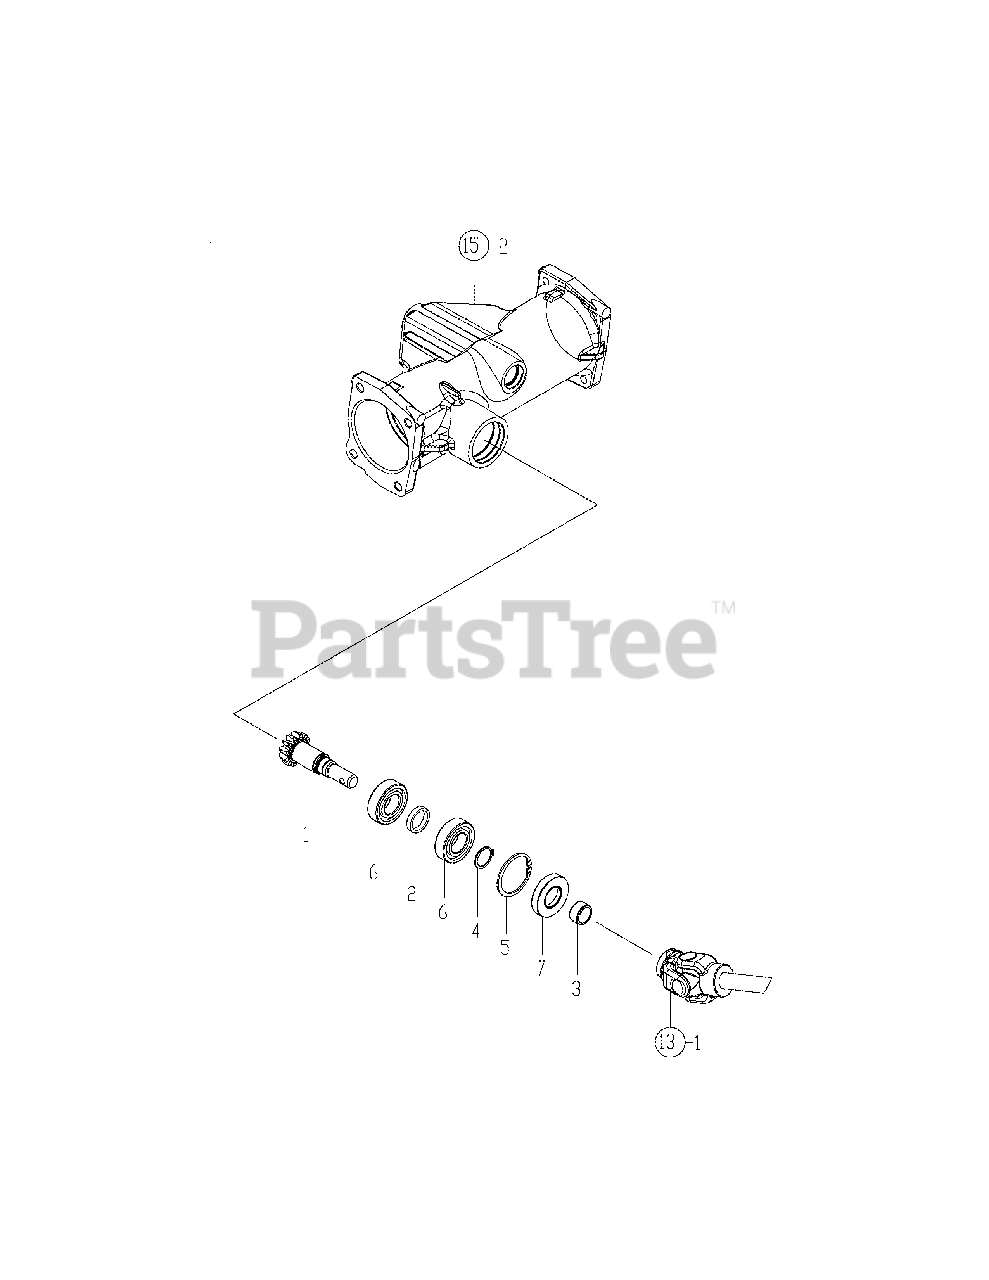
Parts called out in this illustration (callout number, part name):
2	Collar 30X25X5.7
3	Sleeve, 202513
6	Bearing, 6205 Ntn
7	Seal, Tc255210
